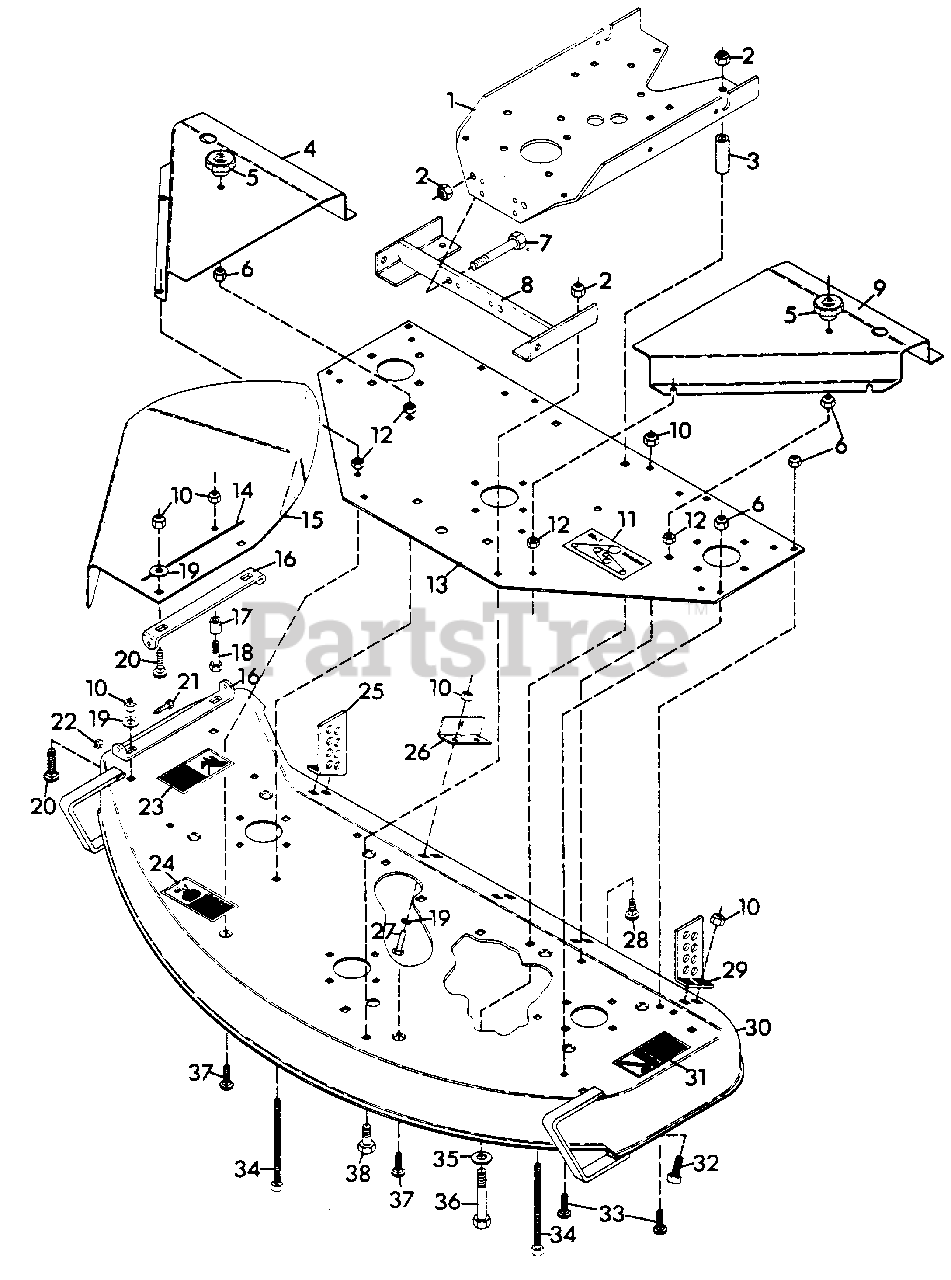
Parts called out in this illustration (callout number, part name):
1	SUPPORT, GEAR HOUSING
2	NUT, LOCK 1/2-13
3	SPACER, .510X.840X2.43
4	COVER, PULLEY R.H.
5	KNOB
6	NUT, LOCK 5/16-18
7	BOLT, HEX 1/2-13X1.375
8	BRACKET, HEIGHT ADJUSTMENT
9	COVER, PULLEY L.H.
10	NUT, LOCK 3/8-16
11	DECAL, BELT INSTALLATION
12	NUT, JAM 5/16-18
13	PLATE, SUPPORT
14	STRIPE
15	SHIELD, SAFETY EXTENSION 50" MOWER
16	BRACKET, CHUTE
17	STOP, CHUTE
18	BOLT, HEX 3/8-16X1.50
19	WASHER, FLAT .406X.812X.065
20	BOLT, 3/8-16X1.00 RD HD SQ NK
21	BOLT, HEX 1/4-20X.875
22	NUT, LOCK 1/4-20
23	DECAL, DANGER HAND
24	DECAL, WARNING EYE
25	PLATE, REAR ADJUSTMENT
26	BRACKET, LIFT
27	BOLT, HEX 3/8-16X1.00
28	BOLT, 3/8-16X.75 RD HD SQ NK
29	PLATE, REAR ADJUSTMENT
30	WELDMENT, 50" MOWER DECK
31	DECAL, DANGER FOOT
32	BOLT, HEX 3/8-16X1.25
33	BOLT, 5/16-18X.75 RD HD SQ NK
34	BOLT, HEX 5/16-18X3.50
35	WASHER, FLAT .531X1.062X.095
36	BOLT, HEX 1/2-13X3.75
37	BOLT, CARRIAGE 5/16-18X1.00
38	BOLT, HEX 1/2-13X1.25
